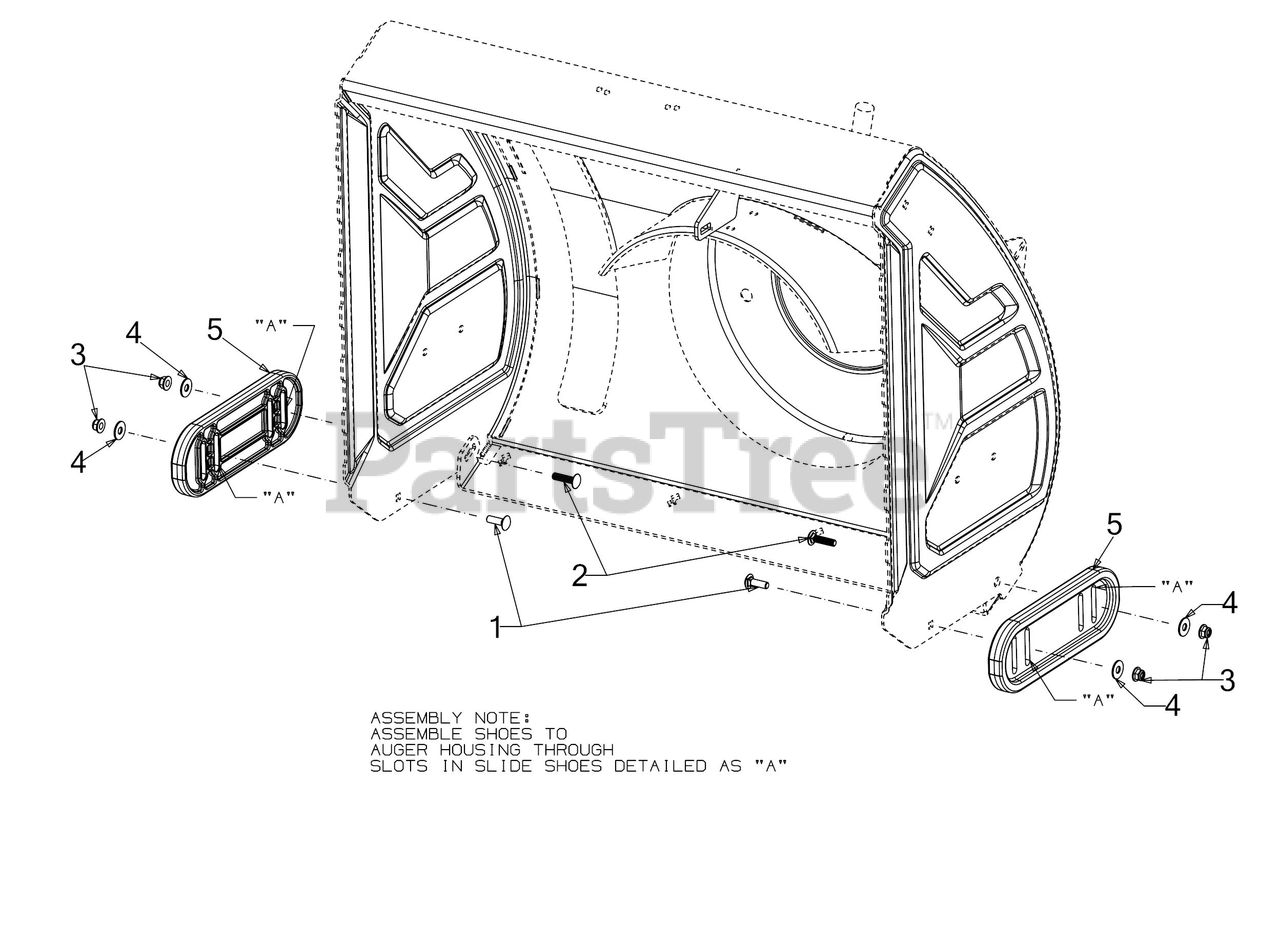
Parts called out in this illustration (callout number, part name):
1	CARRIAGE BOLT 5/16-18 x 1.00
2	CARRIAGE BOLT 5/16-18 X 1.25
3	FLANGE LOCK NUT 5/16-18
4	FLAT WASHER
5	DELUXE SKID SHOE (POLY BLUE)
